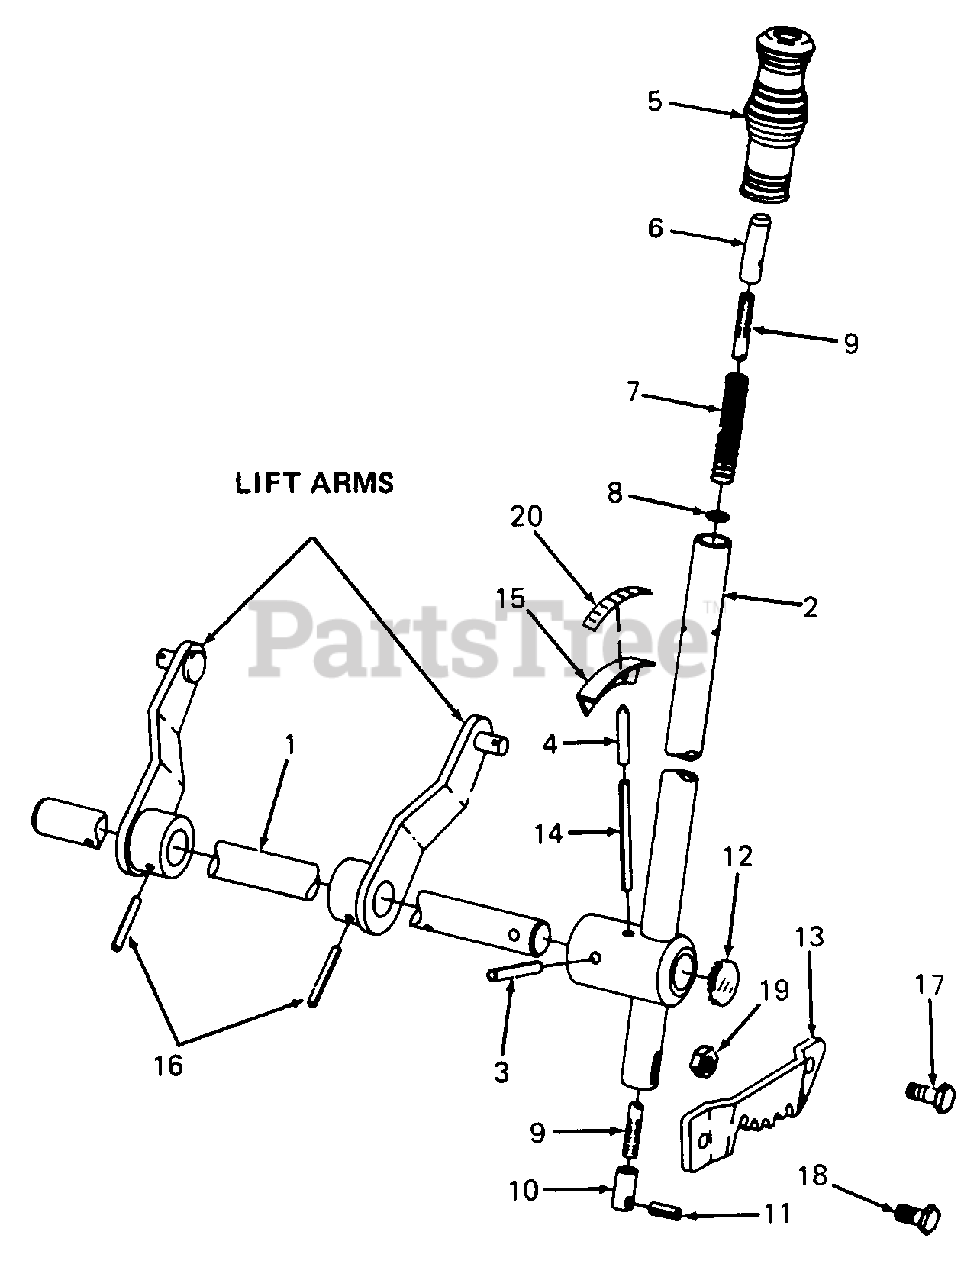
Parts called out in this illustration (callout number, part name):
1	Shaft, Lift
2	Lever, Lift
3	Pin, 3/8 X 1-3/4 Pln Slt-Spr
4	Pointer, Lift
5	Grip, Lift Handle
6	Pin, Release
7	Spring, Lift Handle
8	Washer, .344 X .532 X .06 Hdn Flat
9	Rod, Handle
10	Rod, Handle Release
11	Pin, 5/16 X 1-3/8 Hvy Pln Cld Spr
12	Plug, 1.0 Button
13	Ratchet, Handle
14	Pin, 3/16 X 3 Slotted Roll Spr
15	Bracket, Height Indicator
16	Pin, 1/4 X 1-1/2 Slotted Roll
17	Bolt, 3/8 X 1 GR 5
18	Bolt, 3/8 X 1 GR 5
19	Nut, 3/8 Center L GR 5
20	Label, 5 Position
